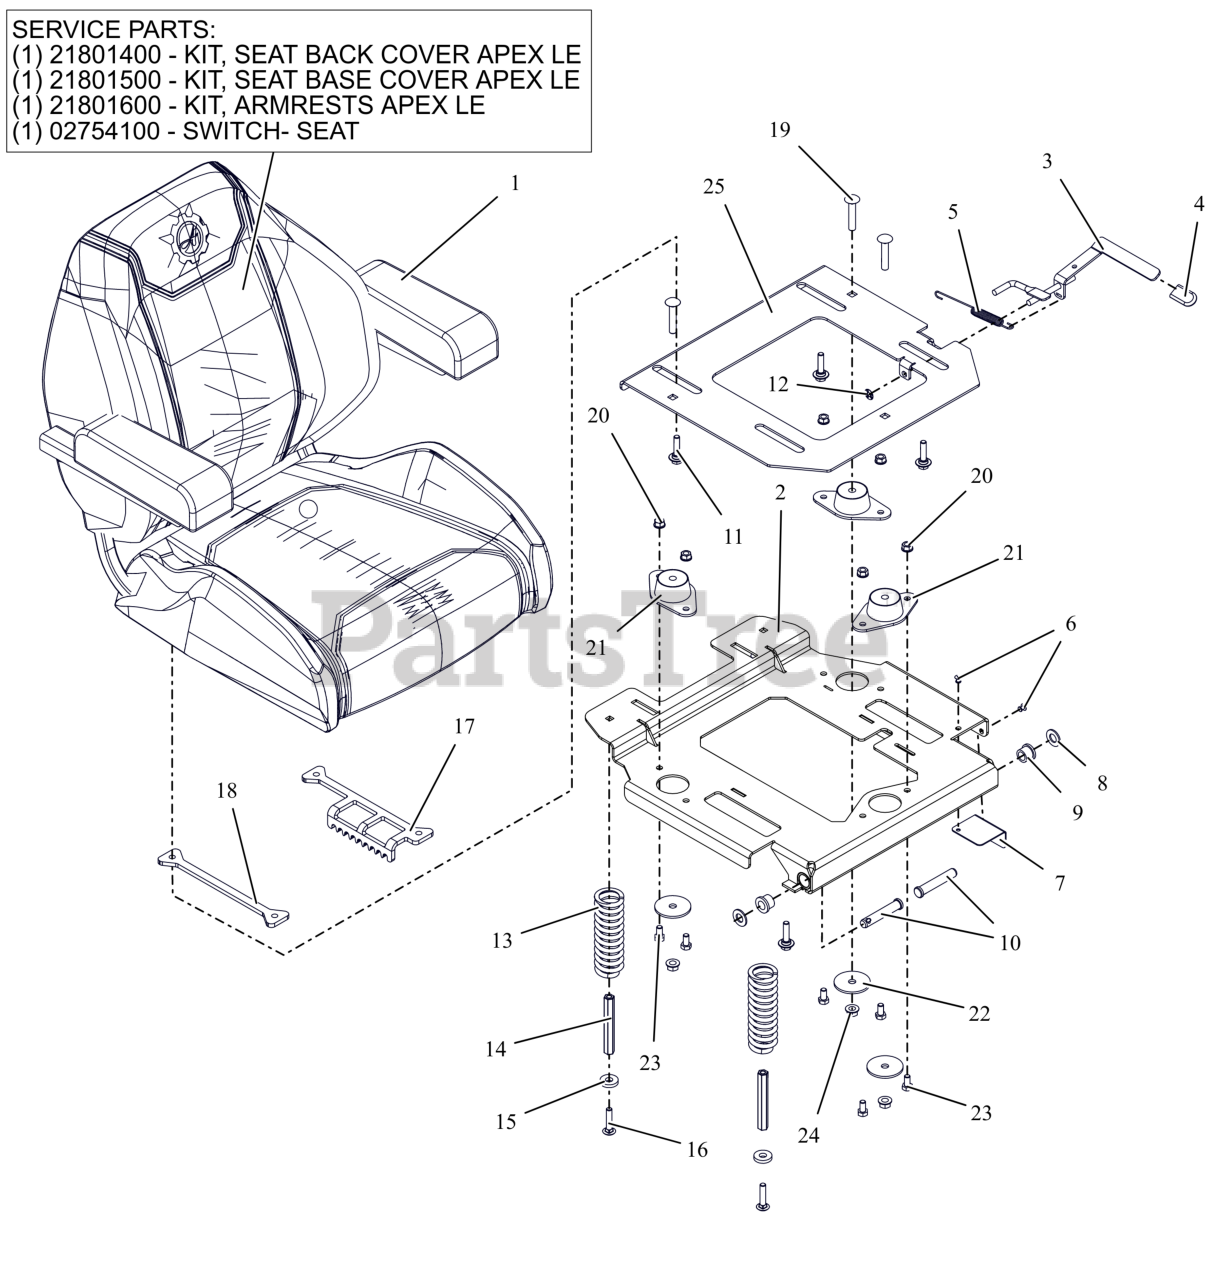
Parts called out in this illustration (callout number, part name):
1	SEAT- APEX LE
1	KIT- SEAT BACK COVER APEX LE
1	KIT- SEAT BASE COVER APEX LE
1	KIT- ARMRESTS APEX LE
1	SWITCH- SNAP MTG N.O.
2	WLDMT- ISO MTG PLATE 3 PT
3	WLDMT, SEAT SLIDE LEVER
4	GRIP, SEAT LEVER, GREY
5	SG-TENS .06X.482X5.35
6	RIVET, .1875 AL/AL .126-.250
7	GUARD- SEAT
8	WSHR-FL-NYL .518X1.000X.080
9	BSHG, FLG .516X.750X.625X.937
10	PIN-CLIC .50X2.70X2.31 -ZCC
11	BOLT SHLDR .31-18 X .175
12	NUT-PUSH .312
13	SPRING, COMPRESSION SEAT 224LB
14	NUT, COUPLING 5/16X18 X 3.75
15	WSHR, FLT .406X1.00X.188 ZCC
16	BLT,RHSN .31-18X1.50 G5 ZCC
17	PLATE, SEAT ADJ (BLACK)
18	PLATE, ADJ SEAT SLIDE (BLACK)
19	BLT,RHSSN.375-16X2.00 G5 ZCC
20	NUT,LK-CTR-FLG .31-18 GF ZCC
21	MOUNT, FAIL-SAFE COMPRESSION
22	WSHR-FL-STL 0.406X2X0.125 ZCC
23	BLT, HEX .31-18X.625 G5 ZCC
24	NUT-LK-CTR-FLG .375-16 GF ZCC
25	PLATE- SEAT MTG 3PT (ISO KIT)
